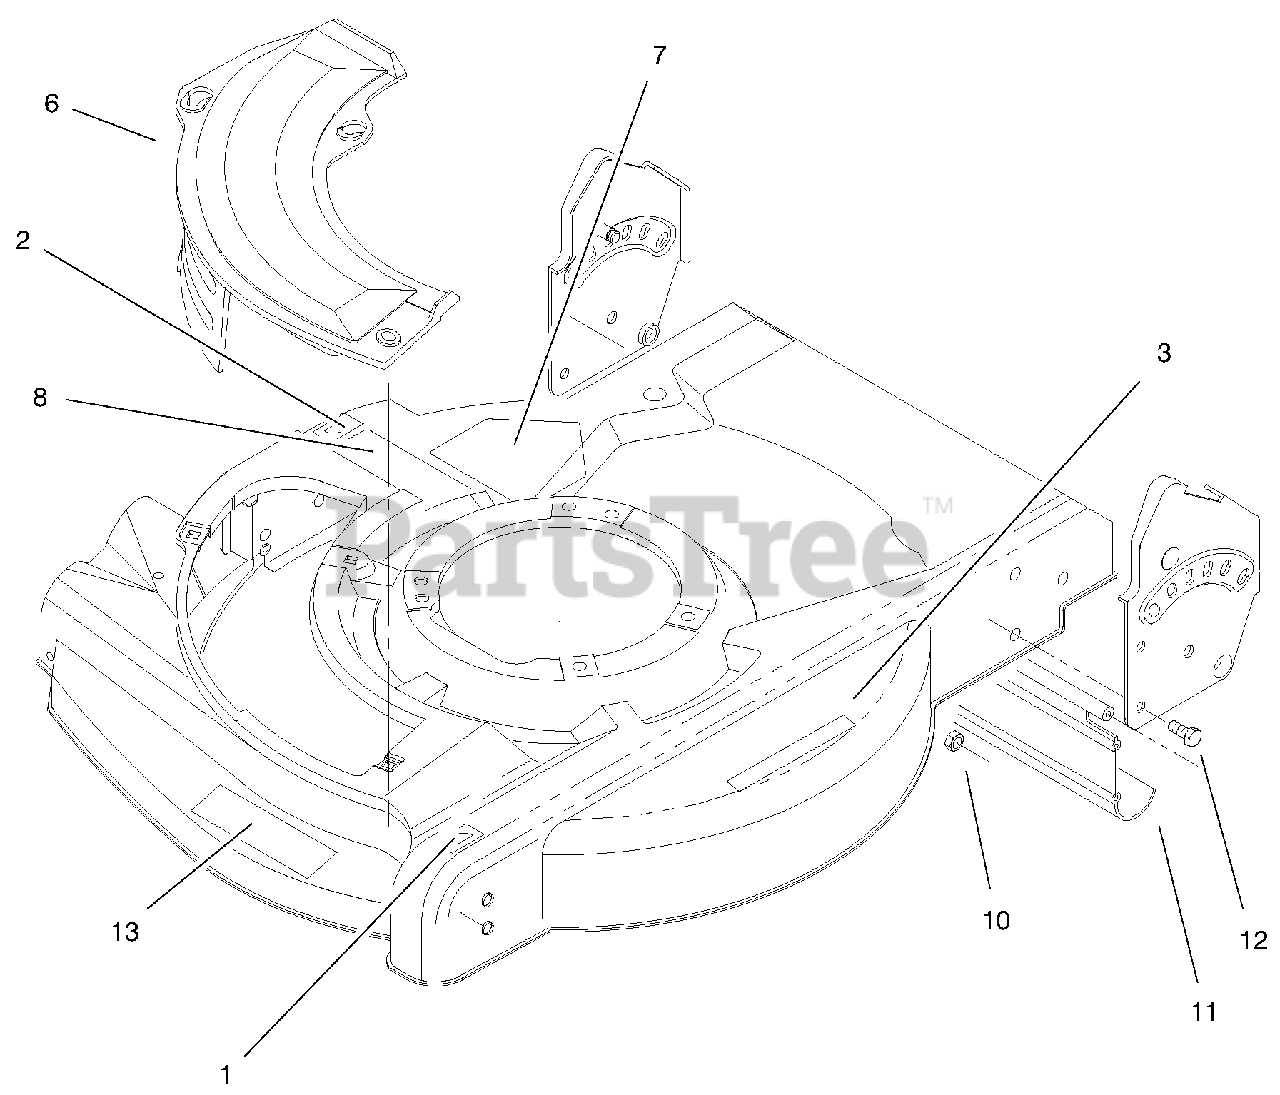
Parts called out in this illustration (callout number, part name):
1	Decal-HOC
2	Decal-HOC
3	Decal-Warning
6	Plate-Cover
7	Decal-Danger
8	Decal-Discharge
10	Nut-Lock
11	Shield-Trailing
12	Screw-HH
13	Decal-Deck
